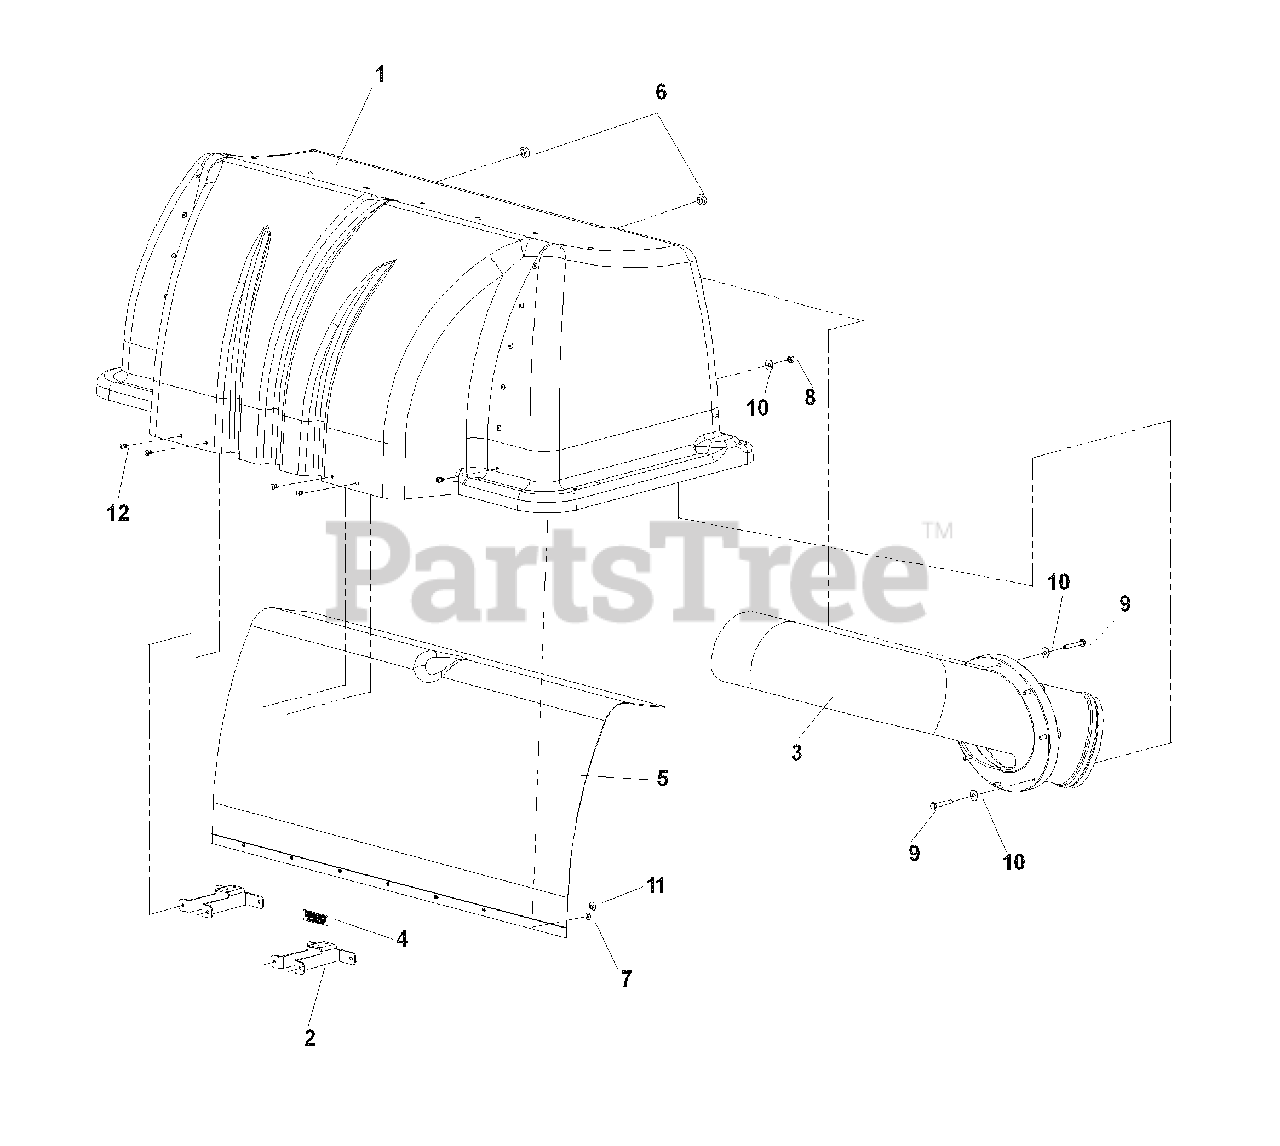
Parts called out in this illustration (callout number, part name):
2	SUPPORT, DRAWLATCH
4	DECAL, VENTILATION
5	MESH, POLYDIAMOND
6	GROMMET, BUMPER
7	WASHER, #10
8	NUT, 1/4-20, NYLOC
9	HCS, 1/4-20x1 3/4
10	WASHER, 1/4
11	RIVET, 3/16x1/4
12	RIVET, 3/16, STAVEX
